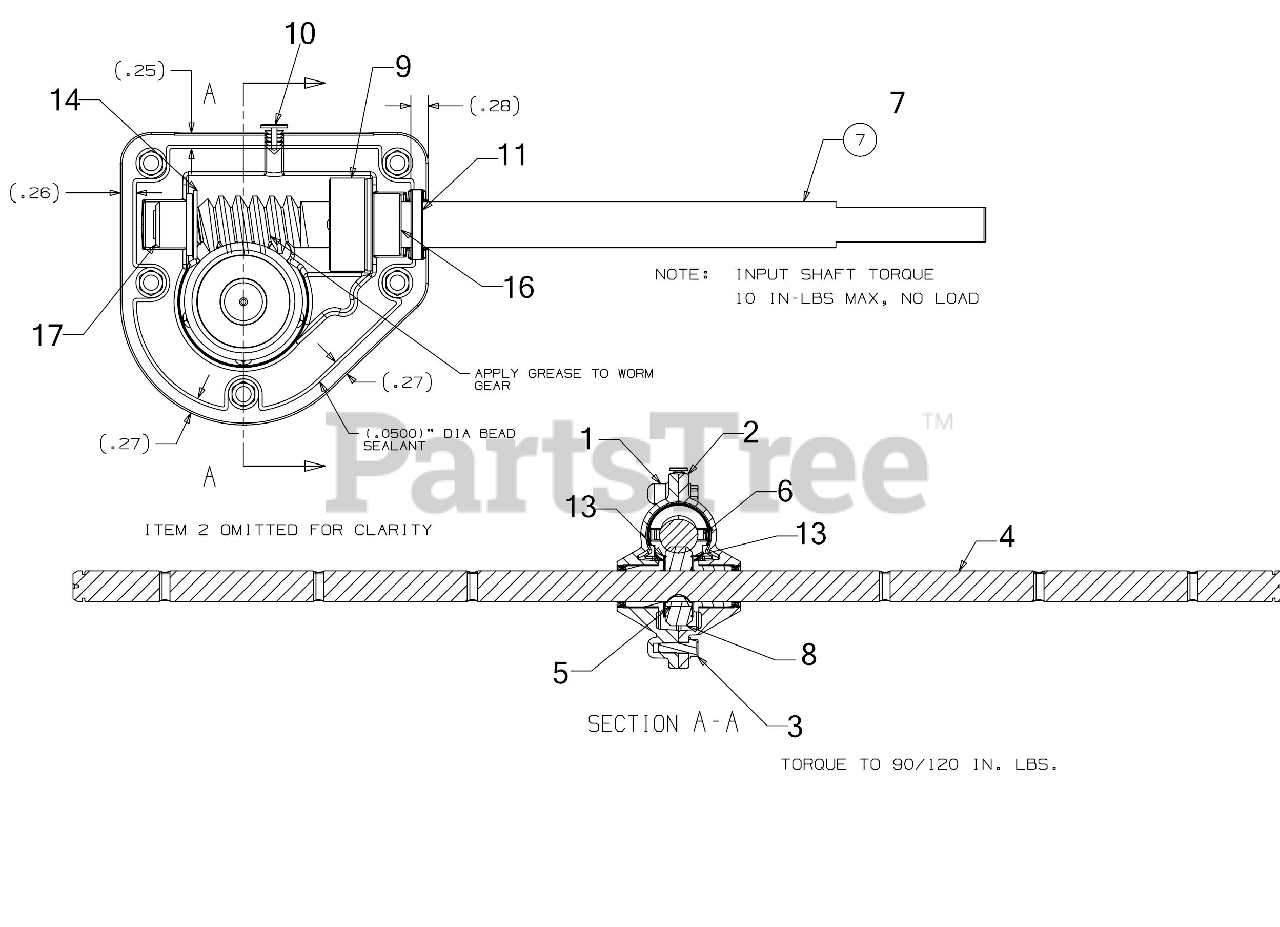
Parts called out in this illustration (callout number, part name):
1	REDUCER HOUSING ASSEMBLY (RH)
2	REDUCER HOUSING ASSEMBLY (LH)
3	SCREW 1/4-20 x .750
4	30" AUGER AXLE
5	KEY 3/16 x 5/8 H
7	WORM SHAFT
8	WORM GEAR 20T
9	COLLAR-THRUST .756ID x .600
11	OIL SEAL .75 x 1.131 x .188
13	THRUST WASHER
14	FLAT WASHER
16	FLANGE BEARING
17	FLANGE BEARING
